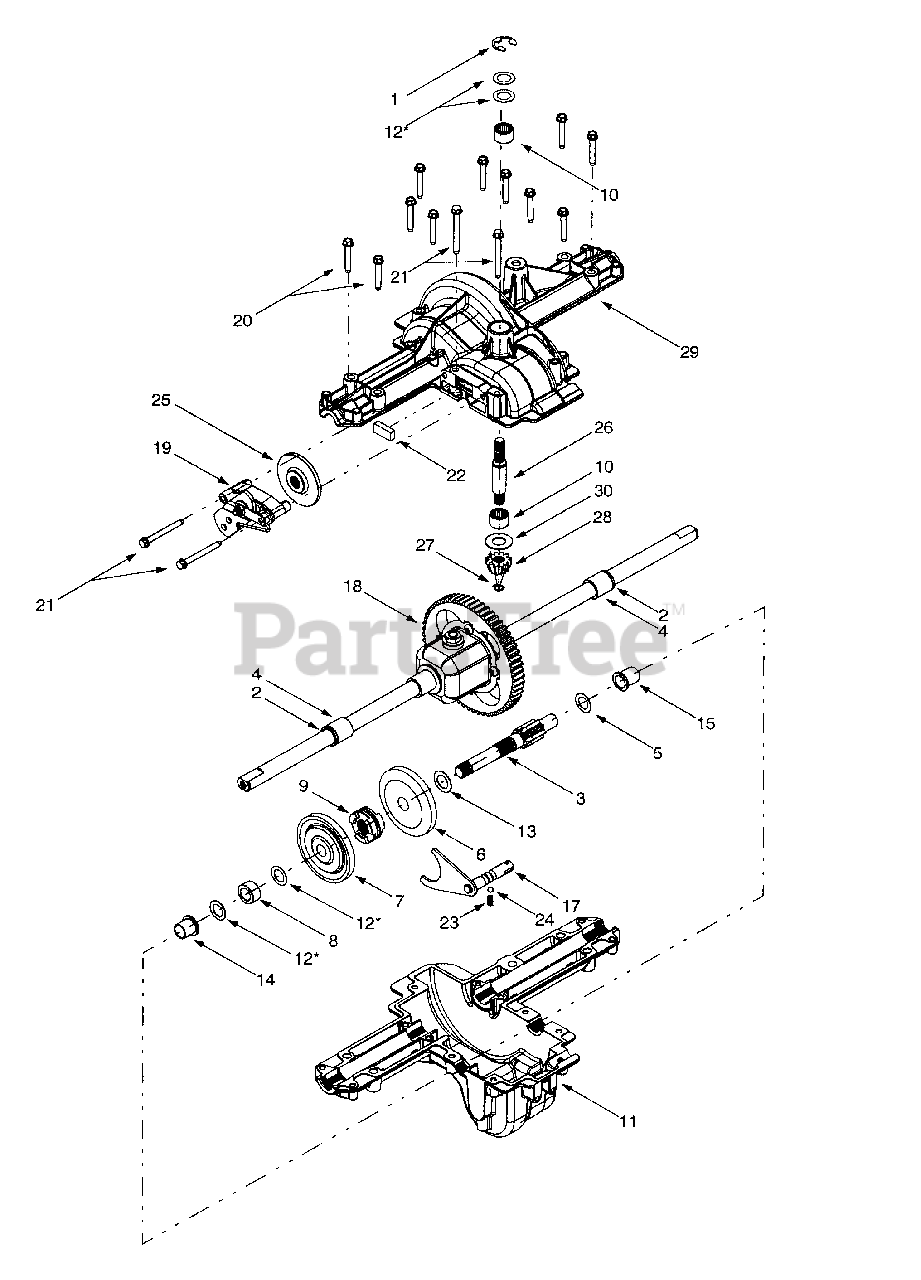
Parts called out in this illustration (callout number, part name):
1	E-ring, .75
2	Seal, .75 x 1.0 x .125
3	Drive Shaft
4	Sleeve Bearing, .75 x .1 .0 x 1.0
5	Thrust Washer, 1.0 x .632 x .0
6	42-tooth Bevel Gear
7	42-tooth Bevel Gear
8	Spacer, .633 x 1.0 x .513
9	Clutch Collar
10	Needle Bearing, .625 x .875
11	Lower Housing
13	Flat Washer, .70 x 1.125 x .031
14	Flange Bearing, 5/8 x 3/4 x 3/4
15	Flange Bearing, 5/8 x 3/4 x 15/16
17	Detent Shaft Assembly
18	Differential Assembly
19	Brake Assembly
20	Self-tapping Screw, 1/4-20 x 1.625
21	Self-tapping Screw, 1/4-20 x 2.375
22	Brake Pad
23	Compression Spring
24	Detent Ball
25	Brake Disc
26	Input Shaft
27	Retaining Ring, .437
28	14-tooth Bevel Pinion
29	Upper Housing
30	Thrust Washer, .635 x 1.25 x .042
